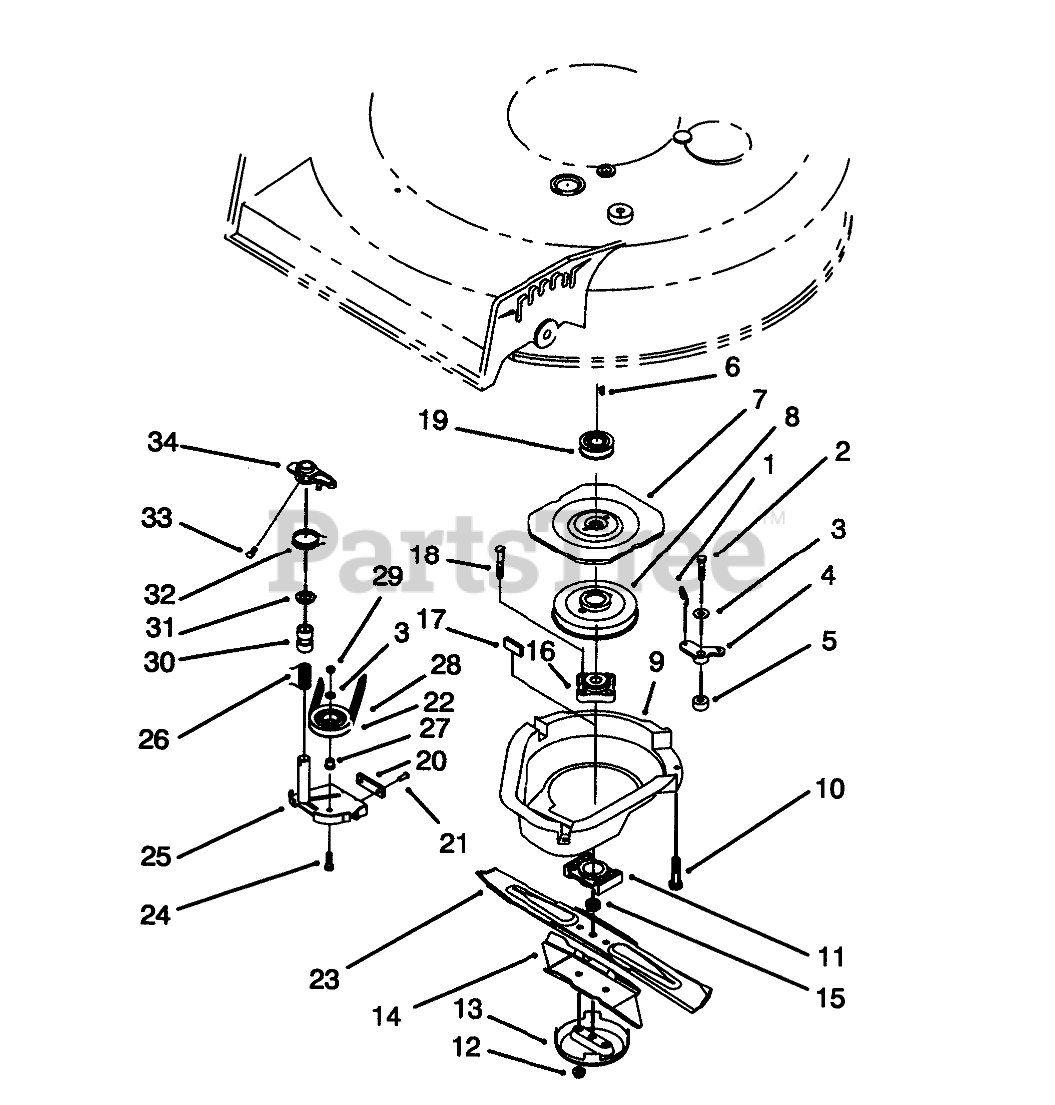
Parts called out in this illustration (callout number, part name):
1	LINK-CONTROL
2	SCREW-HH
3	WASHER-PLAIN
4	BELLCRANK
5	SLEEVE-BELLCRANK
6	KEY-WOODRUFF
7	Flywheel
8	Drum-Brake
9	SHIELD BBC
10	SCREW-HWH
11	SPACER-BLADE
12	NUT-LOCK
13	CUP-SCALP, ANTI
14	Accelerator
15	NUT-LOCK, NI
16	HUB ASM
17	DAMPENER-VIBRATION
18	BOLT-BLADE
19	PULLEY
20	Pad-Brake
21	.185 DIA X .375 RT +
22	PULLEY-IDLER
23	Blade
24	SCREW-HH
25	Brake Plate (Incl. Ref. #20 & 21)
26	SPRING-TORSION
27	HUB-PULLEY, IDLER
28	V-BELT
29	NUT-LOCK, NI
30	BEARING
31	WASHER
32	SPRING-TORSION
33	SCREW-HH
34	LEVER
